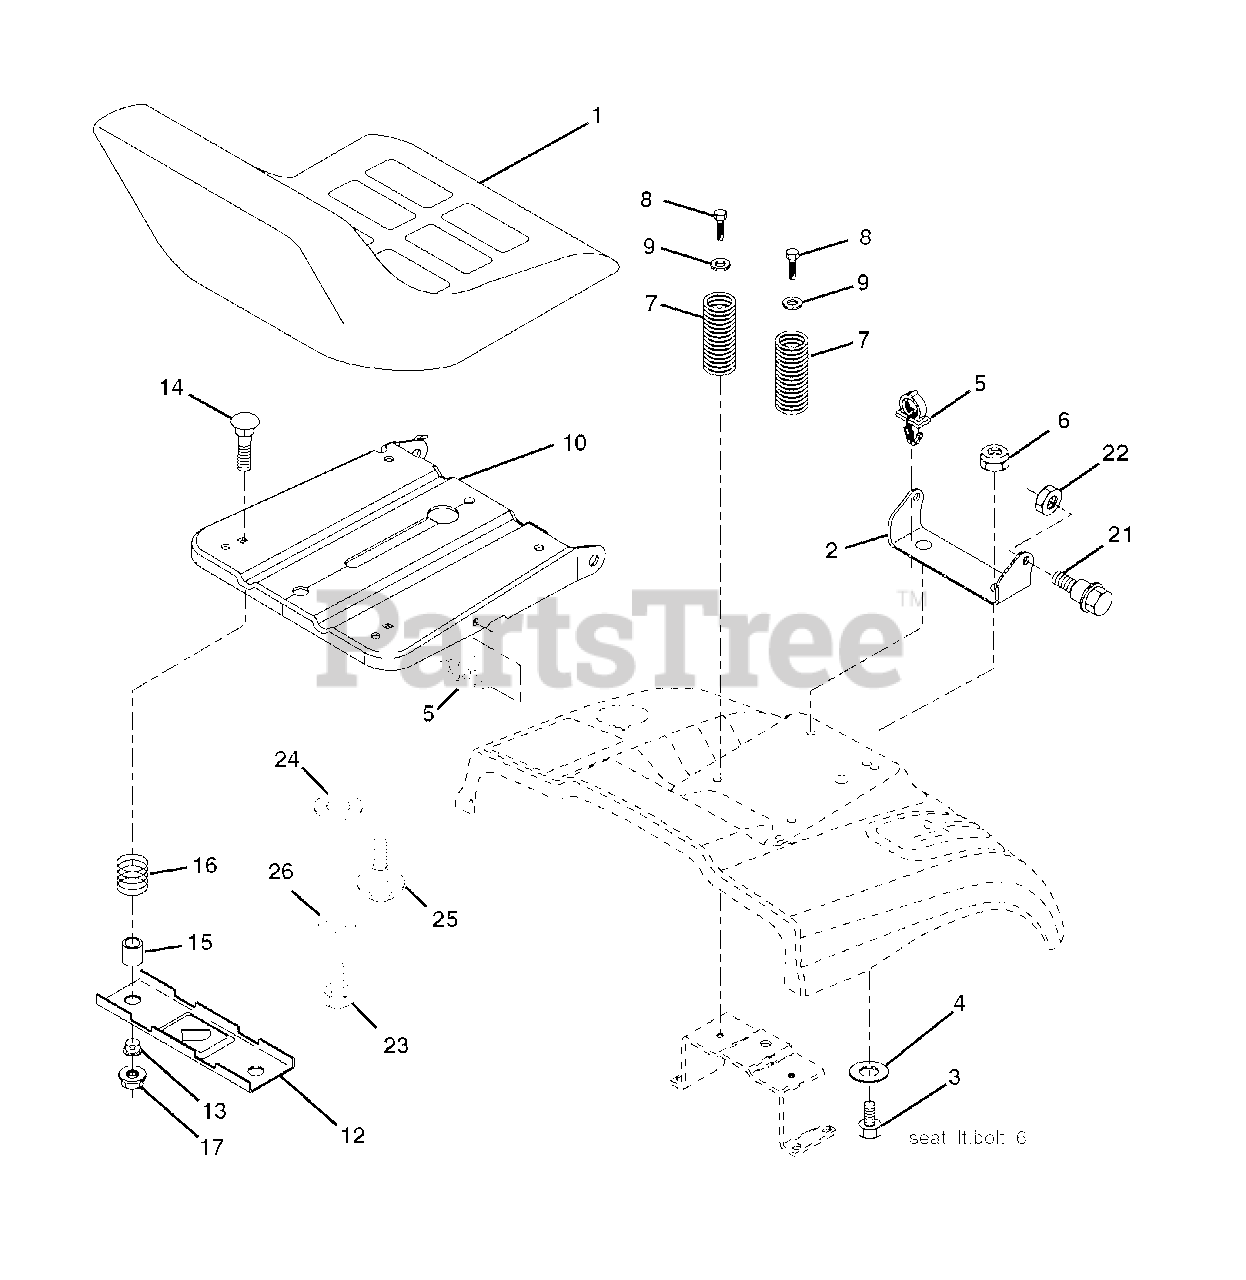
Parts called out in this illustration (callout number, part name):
1	SEAT.XG090.BLK.KB/BLT.NO-LOG
2	SEAT PIVOT BRKT
4	WASHER PM
5	PUSH CLIP
6	NUT
7	SPRING COMPRESSION
8	SCREW 3/8-16X1
9	WASHER
10	PAN.ASM.SEAT.1SLOT
12	BRKT.MNTNG.SWITCH.SEAT
14	BOLT.ROUND.HEAD.SQUARE.NECK
15	SPACER SPLIT 28X.96
17	NUT T
21	BOLT.SHOULDER.5/16-18
22	NUT.71038.31-18.HEX.NYLOCK
23	BOLT.HEX.BLACK
25	BOLT,SHOULD
26	LOCKWASHER
